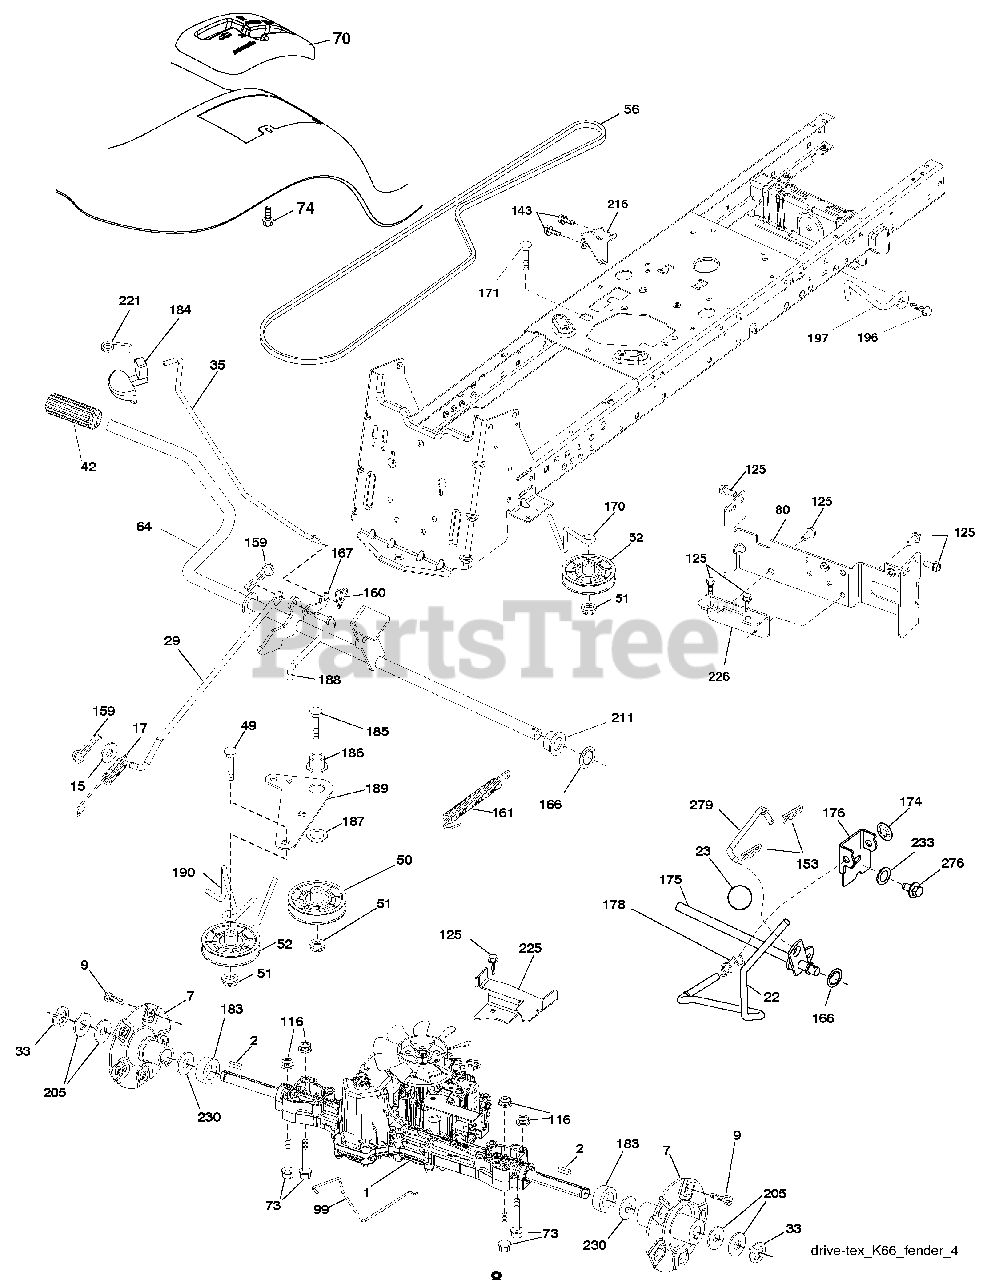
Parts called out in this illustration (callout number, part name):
1	Transaxle, TuffTorq K66 AD
2	Key
7	Hub Asm. Wheel
9	Bolt Hub Wheel
15	Washer 13/32 x 13/16 x 16 Ga.
17	Spring, Brake
22	Rod Shift
23	Knob
29	Rod, Brake
33	Ring E
35	Rod, Brake, Park
42	Cover, Foot Pedal
49	Bolt
50	Pulley Idler Flat
51	Lock Nut 3/8-16
52	Idler V-Groove 910" Offset
56	V-Belt, Drive
64	Shaft Asm. Pedal Brake Control
69	Washer 1 1/32 x 1 5/8 x 16 Ga.
70	Console Shift
73	Bolt Hex Flghd 5/16-18 Gr. 5
74	Screw Hx Wsh Hi-Lo 1/4 x 1/2 unc
80	Strap Torque
99	Rod Bypass
116	Nut Lock Hex Flange 5/16-18
125	Screw 5/16-18 x 3/4
143	Screw 5/16-18 x 1/2
153	Retainer Spring
159	Pin Cotter 1/8 x 3/4
160	Retainer Clip
161	Spring, Return, Clutch
166	Nut Push .625
167	Latch Brake Parking
170	Keeper Belt Centerspan
171	Bolt
174	Nut Push
175	Shaft Asm. Shift
176	Arm Clevis Rod Shift
178	Spring Shift
183	Spacer Axle
184	Handle Parking Brake
185	Bolt
186	Spacer Retainer
187	Washer
188	Link Clutch Ground Drive
189	Bellcrank Ground Drive
190	Keeper Bellcrank Ground Drive
196	Screw 3/8-16 x 1
197	Bracket Clutch Anti-Rotation
205	Washer 1-1/32 x 1-5/8 x 16 Ga.
211	Bushing Shaft
216	Bracket Pulley Idler
221	Retainer Spring Clip Handle
225	Keeper Belt Trans.
226	Bracket Mount Torque
230	Washer Thrust Axle
233	Washer Serrated
276	Bolt Fin. Hex 7/16-14 x 1 Gr. 5
279	Link Asm. Shift
